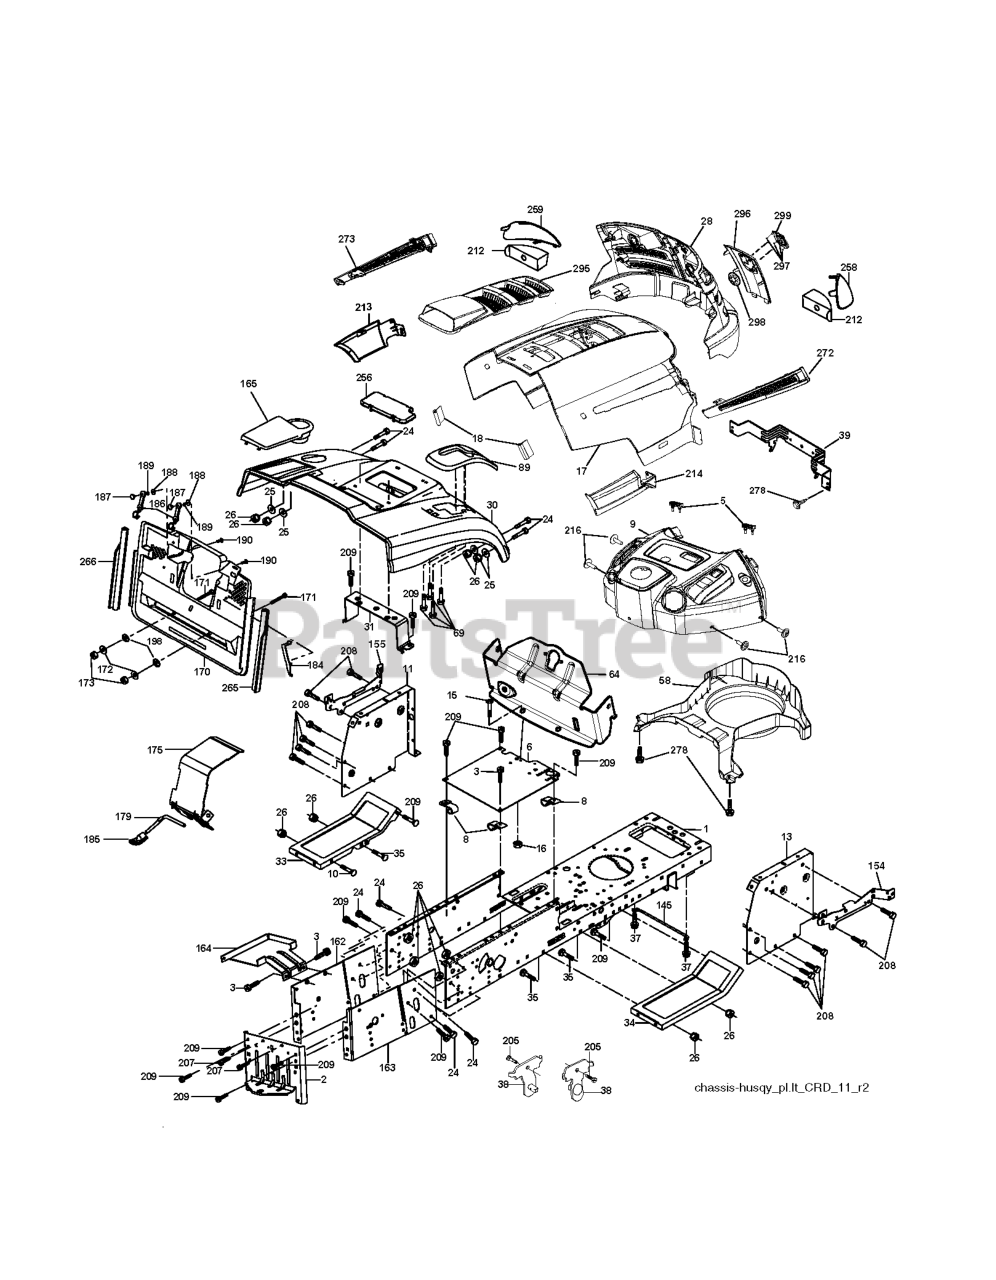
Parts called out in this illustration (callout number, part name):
2	DRAWBAR
3	SCREW 3/8-16X3/4
5	BUMPER DASH
6	PLATE
8	CLIP,INSULATOR
10	BOLT D
11	PANEL.DASH.LH.LTX
13	PANEL ASM, DASH RH
15	Screw, Machine, Truss Head 5/16-18 UNC x 3/4
16	NUT
17	HOOD
18	BUMPER.HOOD.TEX.HUSQVARNA
25	WASHER
26	NUT
28	RP GRILLE/LENS ASM.
30	CONSOLE.CRD.AUTO.GRY
31	BRACKET SUPPORT FENDER
33	FOOTREST PNT LH
34	FOOTREST PNT RH
37	Screw 5/16-18 x 1/2 Hex, Self Tapping 5/16-18 x 1/2
38	BRACKET ASM PIVOT MOWER REAR
39	BRACKET PIVOT
69	SCREW.HI-LO.CONSOLE
89	CONSOLE.CRD.AUTO.GREY.2005
145	ROD.PIVOT.HOOD
162	BRACKET
163	BRACKET EXTEN CHASSIS RH CRD
165	RP.COVER.BATTERY.CRD.GREY
172	WASHER
175	DOOR TRAP
179	ROD PIVOT FBI
184	BRACKET.ACTUATOR.BAGGER.SRD
186	LATCH ASSY
187	WELDNUT
189	LOCKWASHER #10
190	SCREW
207	SCREW, 5/16-18 X 1/2
208	SCREW 3/8-16X1/2
209	SCREW, 3/8-16X3/4
212	INSERT REFLECTIVE
213	SKIRT SIDE LH
214	SKIRT SIDE RH
216	SCREW HEXWSHR 1/4-20X3/4
256	COVER FENDER CRD
258	LENS.HUSQVARNA LT.RH
259	LENS.HUSQVARNA LT.RH
265	SEALING
266	SEALING
278	SCREW
295	VENT TOP HOOD
296	TRIM
297	CLIP.RETAINER.TINNER.
298	NUT PUSH M
299	RP LOGO
